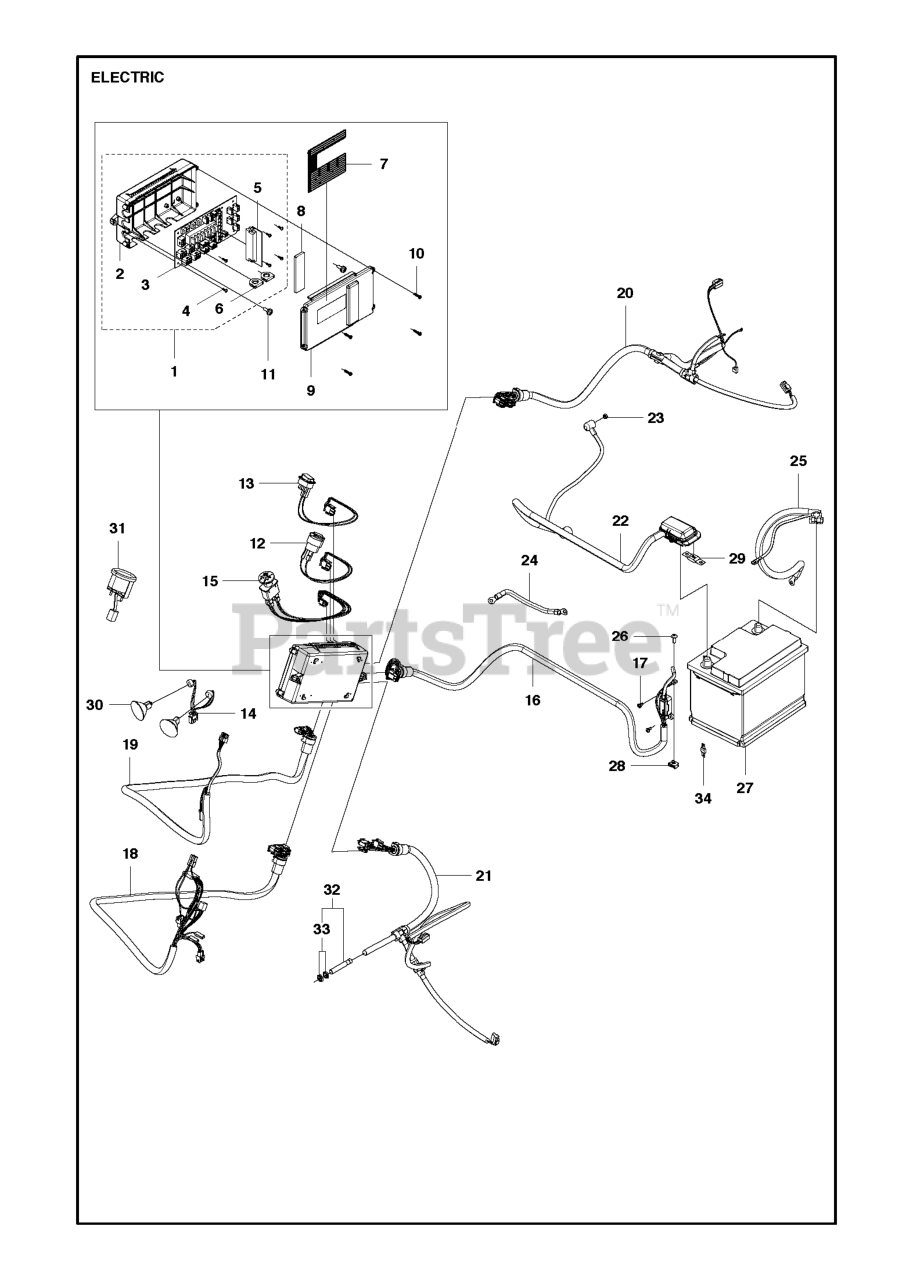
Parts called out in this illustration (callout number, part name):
23	LOCKNUT M6
30	LIGHT
34	FUSE 50A
